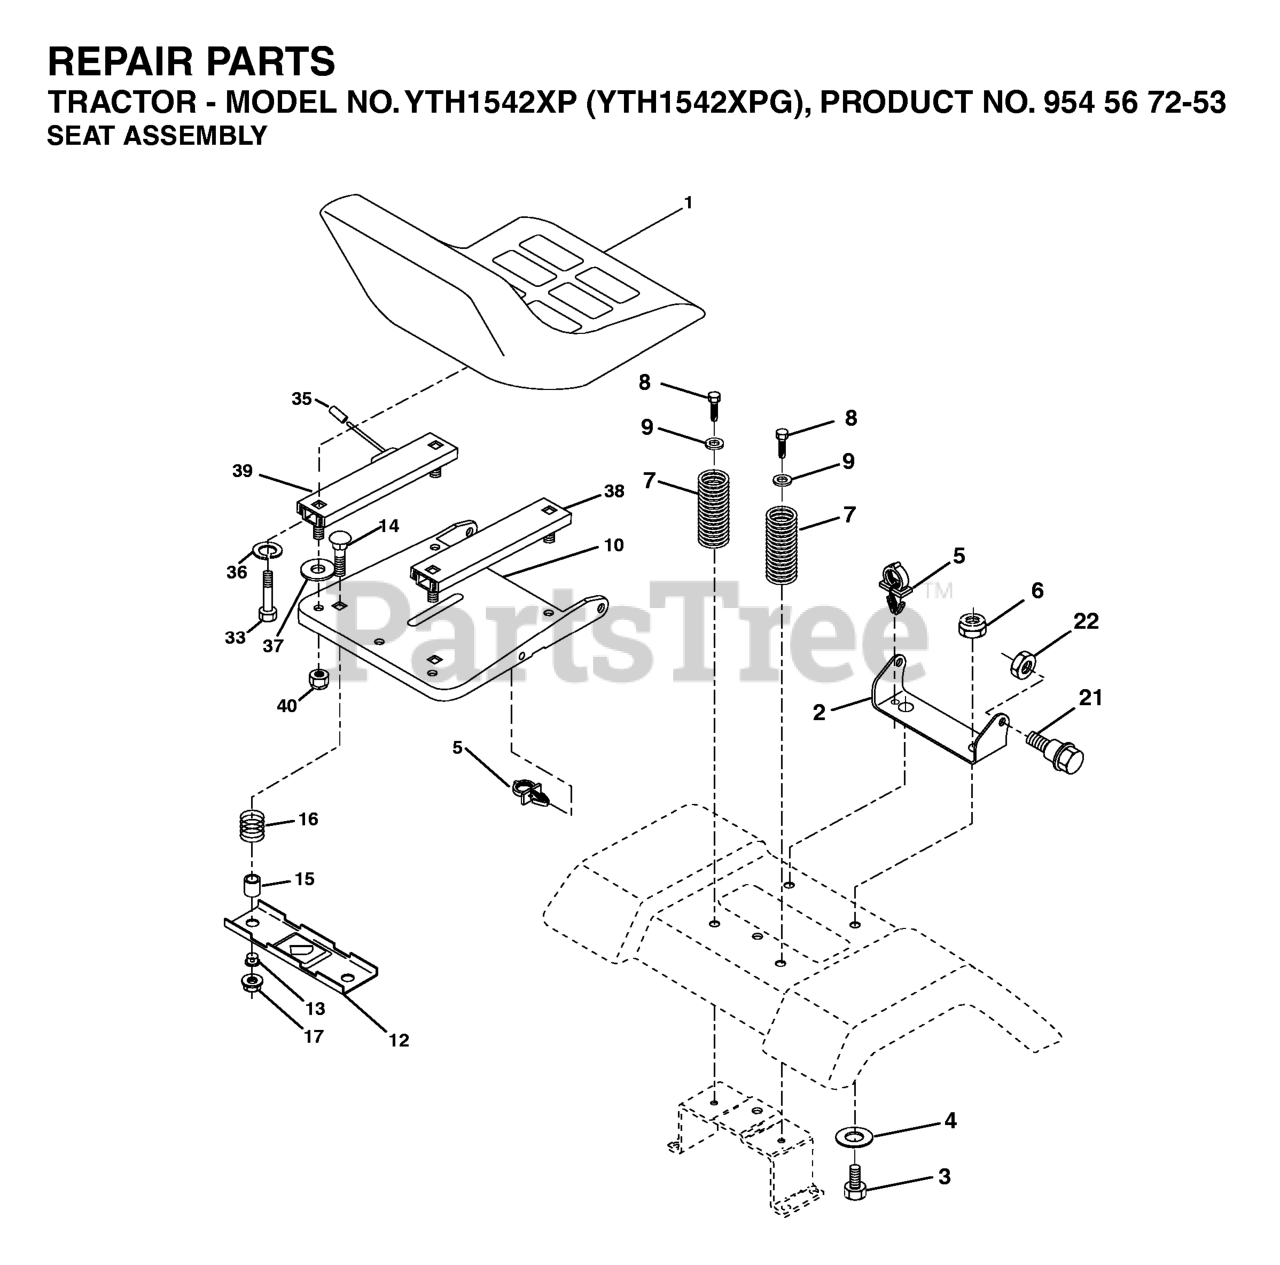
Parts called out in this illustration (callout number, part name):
1	SEAT
2	SEAT PIVOT BRKT
3	BOLT, HEX 3/8-16X1
6	NUT
7	SPRING COMPRESSION
8	SCREW 3/8-16X1
9	WASHER
10	PAN SEAT
12	BRKT SWITCH
14	BOLT.ROUND.HEAD.SQUARE.NECK
15	SPACER SPLIT
16	SPRING COMPRESSED
17	NUT T
21	BOLT.SHOULDER.5/16-18
22	NUT.71038.31-18.HEX.NYLOCK
33	BOLT.FIN.HEX.5/16-18X3/4
35	CAP.VINYL.YELLOW.BUBBLE ASM
38	TRACK SLIDE, SEAT(R)
39	TRACK SLIDE, SEAT(L)
40	LOCKNUT
